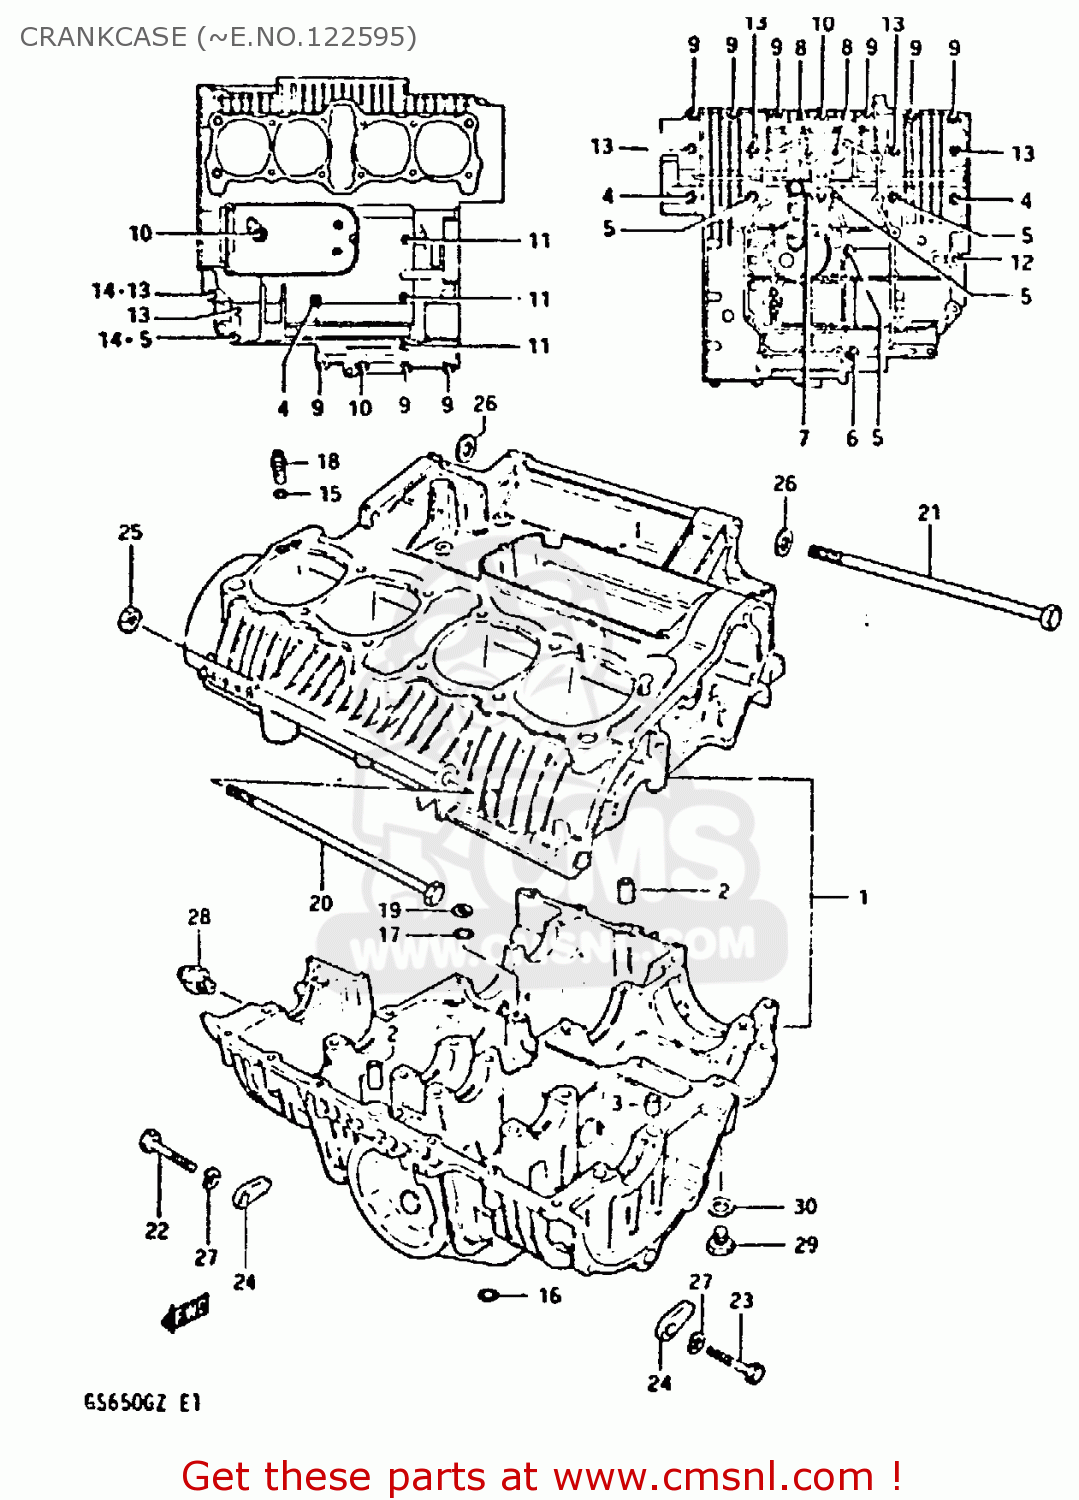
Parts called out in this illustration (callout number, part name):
1	CRANKCASE SET
2	PIN (11X20)(SUS)
3	PIN(10.4X13X22)
4	BOLT
5	BOLT
6	BOLT(8X135)
7	BOLT(8X140)
8	BOLT
9	BOLT
10	BOLT
11	BOLT (6X90)
12	BOLT (8X70)
13	BOLT (8X95)
14	NUT
15	O-RING,OIL GALLERY JET
16	O-RING
17	O RING(D:3.2,ID:12.9)
18	JET(12)
19	WASHER
20	BOLT
21	BOLT 10X250
22	BOLT 10X55
23	BOLT 10X40
24	NUT
25	NUT 10MM
26	WASHER
27	LOCK WASHER
28	SWITCH ASSEMBLY
29	PLUG
30	GASKET(14X19.2X2) (NAS)
